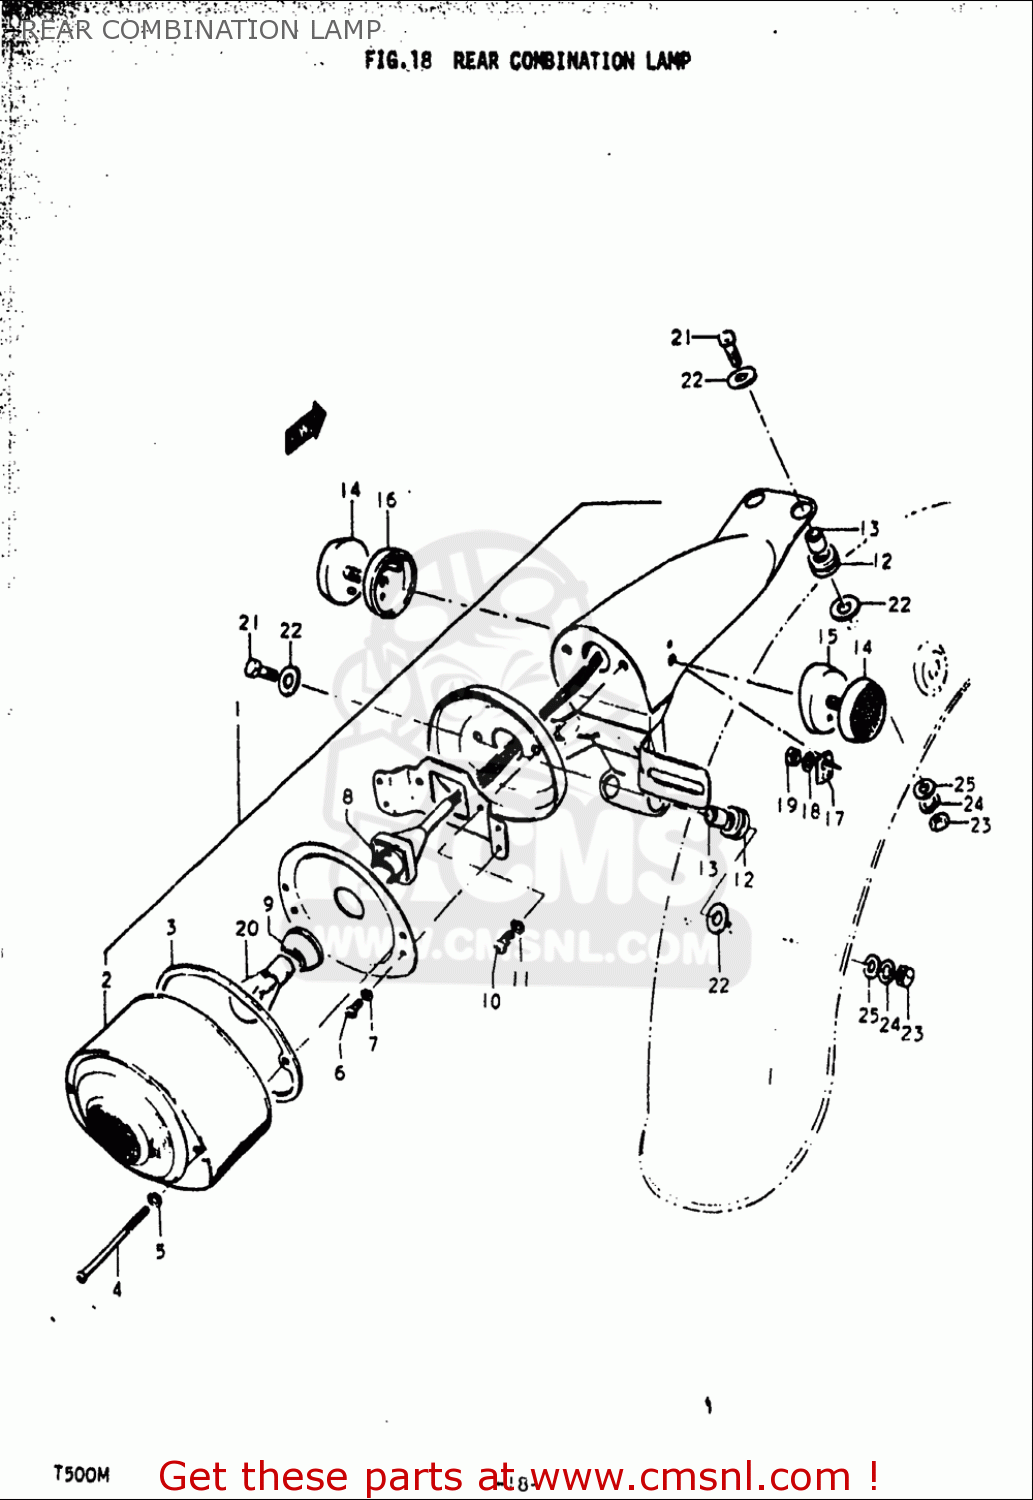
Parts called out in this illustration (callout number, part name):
2	LENS,RR COMBINATION LAMP
6	SCREW
7	WASHER,LOCK
10	SCREW
11	WASHER,LOCK
12	CUSHION
13	SPACER
18	WASHER,LOCK
19	NUT
20	BULB(12V23W)
21	BOLT 6X23
22	WASHER(6.5X20X1.6)
23	NUT
24	WASHER,LOCK
25	WASHER
